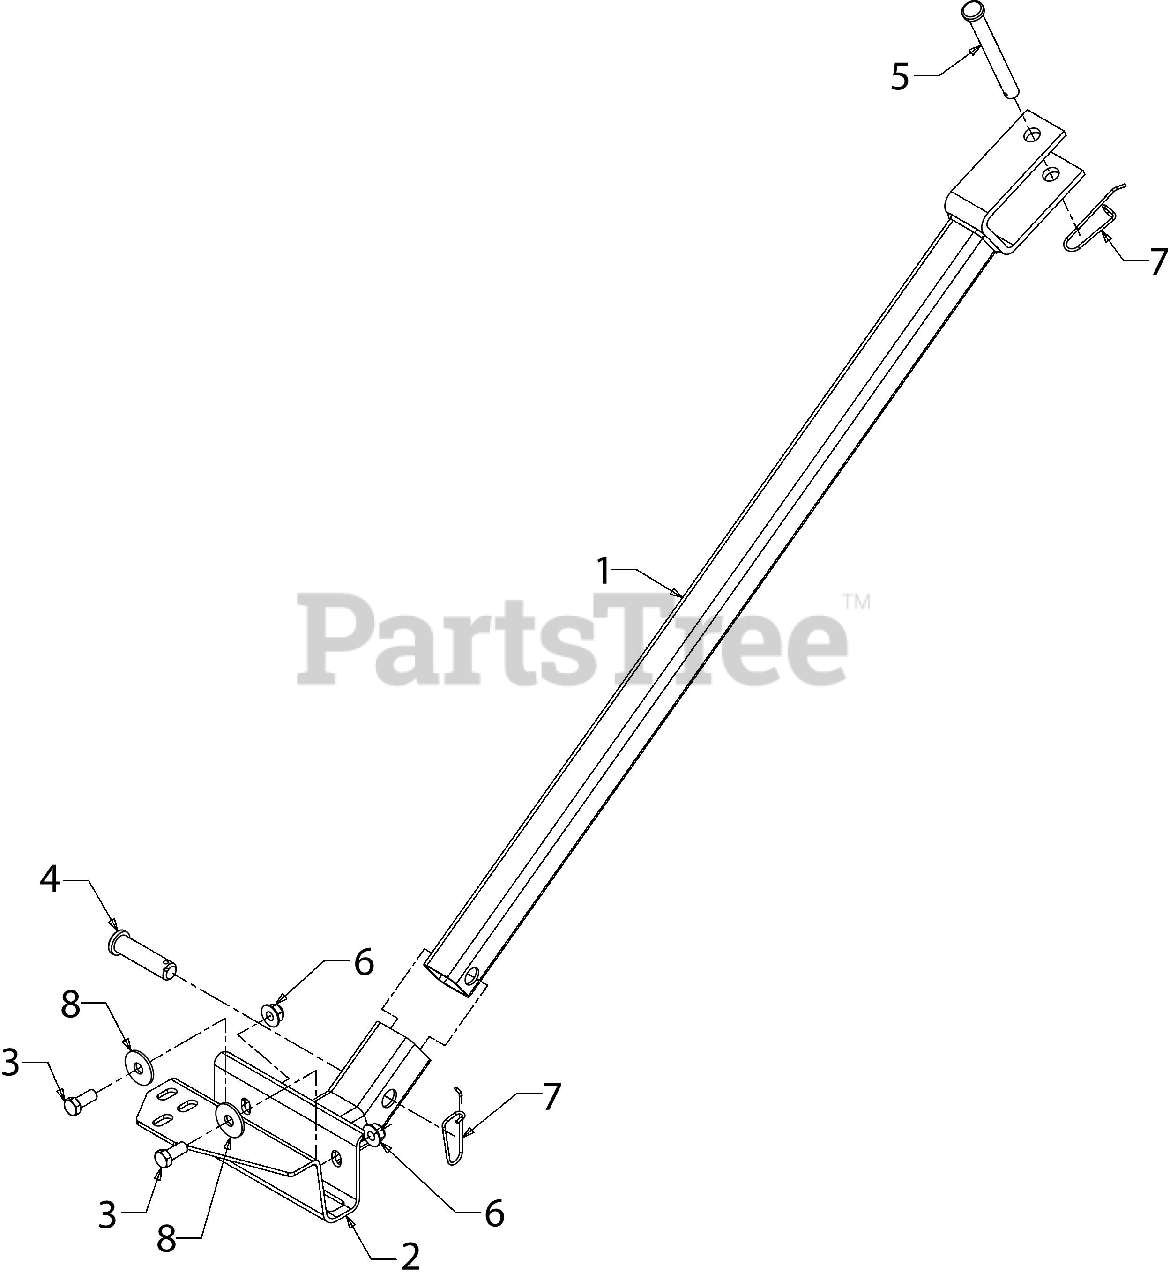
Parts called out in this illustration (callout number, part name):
1	TOW TONGUE BAR
2	TOW BAR BASE
3	SCREW 3/8-16 x .880 GR5
4	CLEVIS PIN .625 x 2.40
5	CLEVIS PIN
7	SPRING PIN
8	FLAT WASHER
